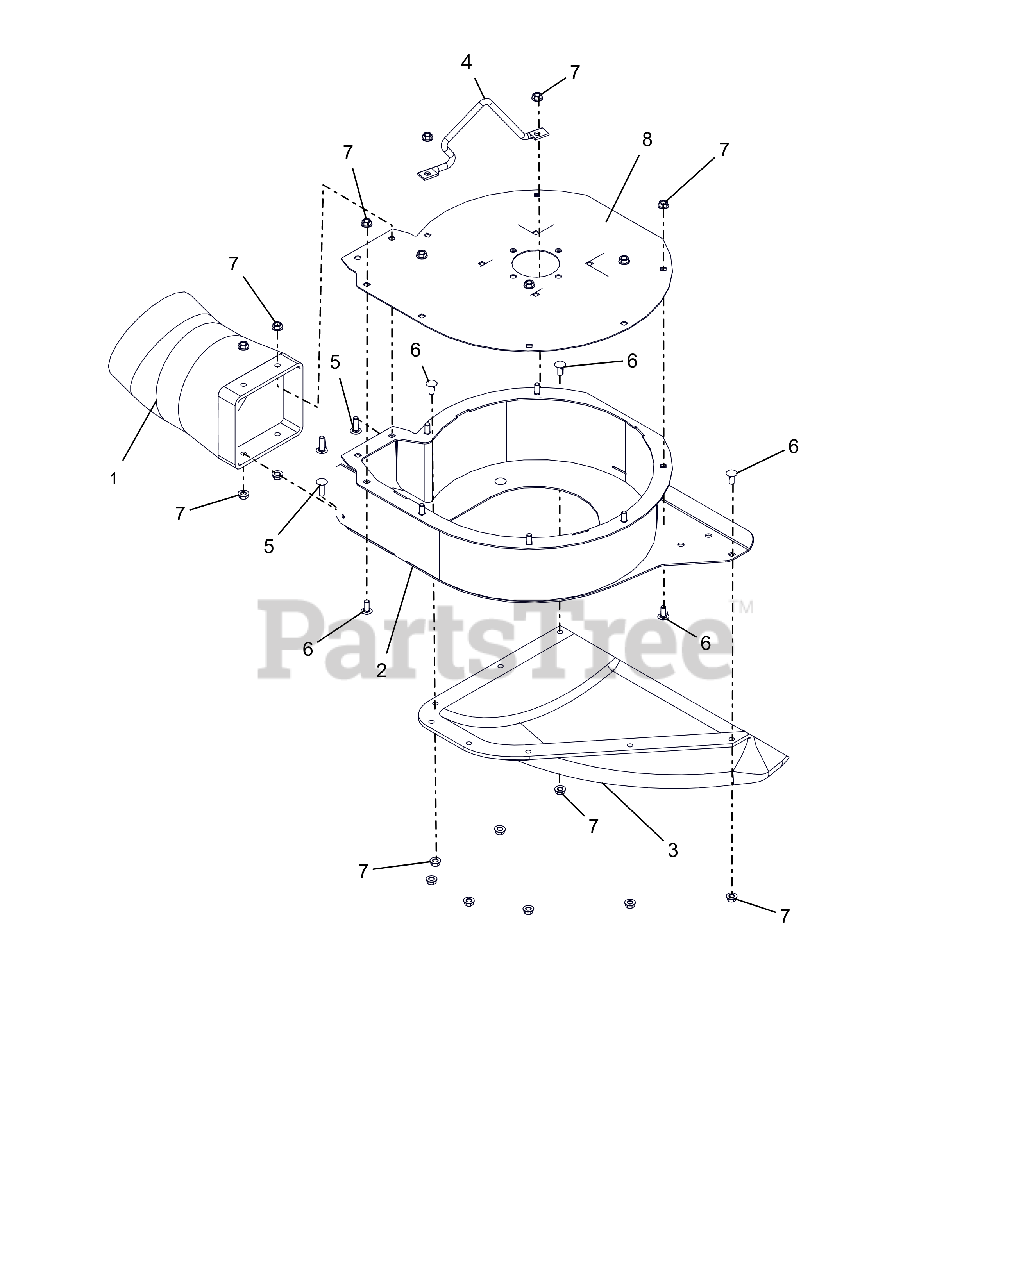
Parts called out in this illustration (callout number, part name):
1	ADAPTER, HOSE
2	WLDMT, BLOWER
3	PLENUM, GRASS PUMP
4	HANDLE, BOLT-ON
5	@BLT-RHDSSQNK .31-18X1.00 G5YZ
6	@BLT-RHDSSQNK .31-18X.75 G5YZ
7	@NUT-LK-TOP-FLG .31-18 YWZC
8	COVER, BLOWER HSG W/SAFETY
